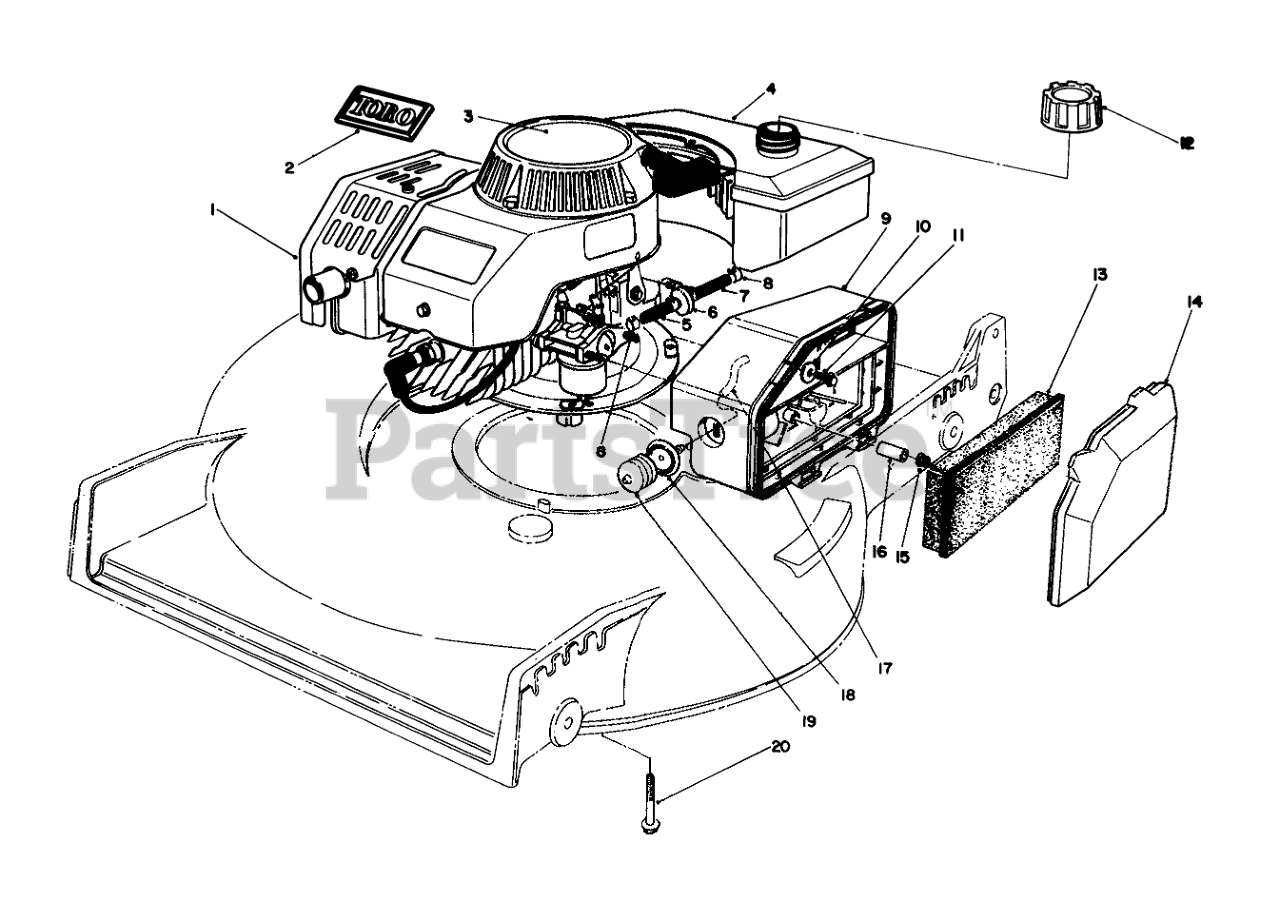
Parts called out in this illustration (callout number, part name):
1	Engine
2	TORO LOGO PLT
3	DECAL
4	Gas Tank Assembly
5	HOSE-FUEL
6	FILTER-FUEL
7	HOSE-FUEL
8	CLAMP-FUEL LINE
9	BODY-AIR CLEANER
10	WASHER-FLAT
11	SCREW-HH
12	GAS CAP ASM
13	ELEMENT-AIR CLEANER
14	COVER-AIR CLEANER
16	SPACER
17	HOSE-PRIMER
18	BODY-PRIMER
19	Bulb Primer
20	SCREW-HHF
